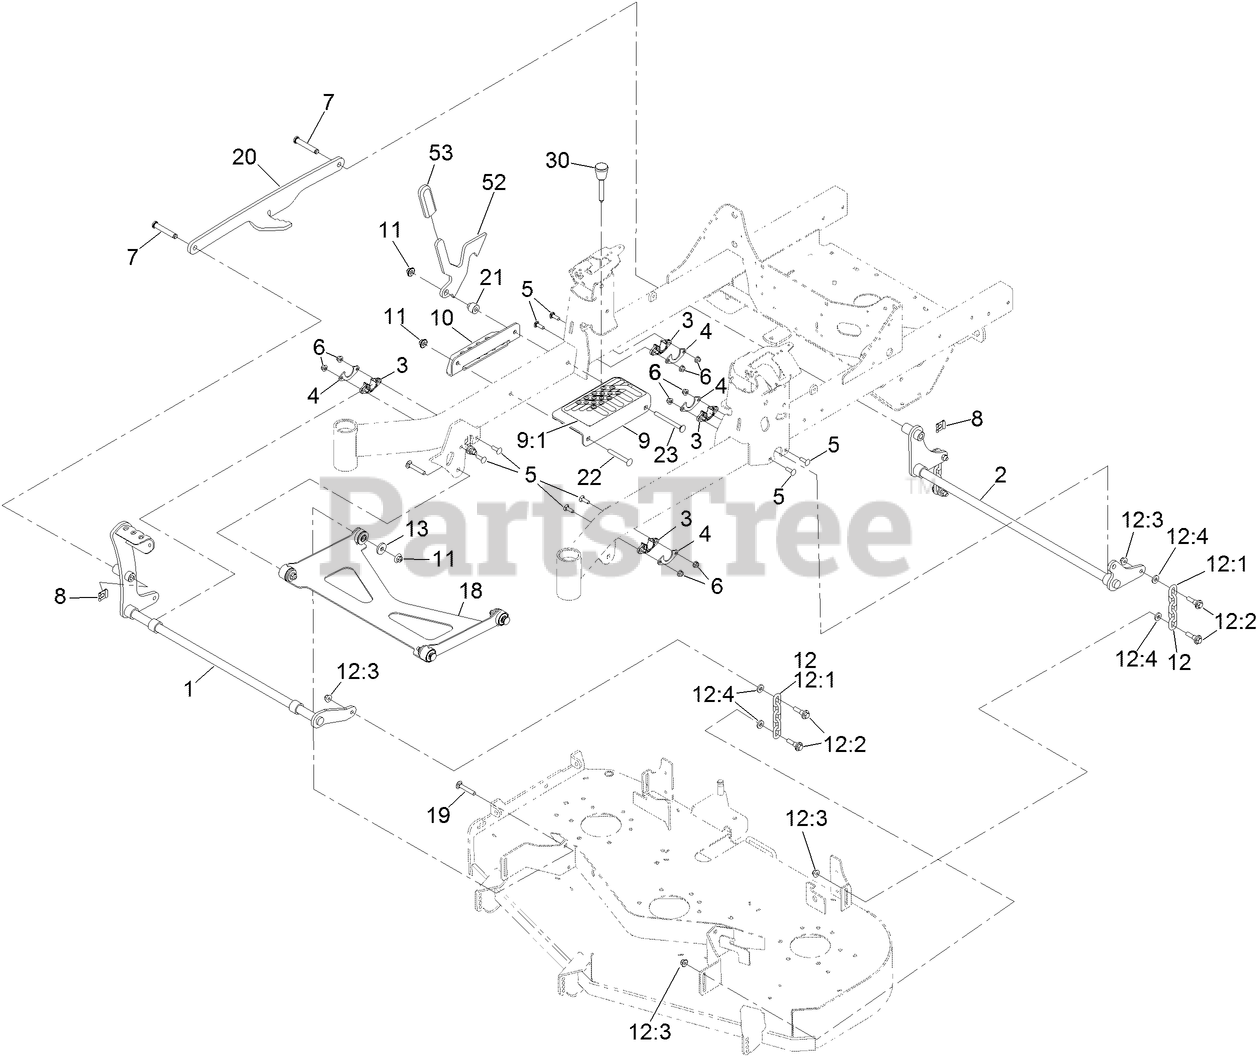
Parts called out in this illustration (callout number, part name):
1	SHAFT-LIFT, DECK
2	SHAFT-LIFT, DECK (REAR)
3	BUSHING-FLANGE
4	GUSSET-LIFT, DECK
5	SCREW-CARR
6	NUT-HF, NI
7	PIN-CLEVIS
8	CLIP-PIN
9	BRACKET ASM
9:1	DECAL-HOC
10	ANGLE-HOC, LOWER
11	NUT-FLANGE, NI
12	DECK CHAIN ASM
12:1	CHAIN-LIFT, DECK
12:2	BOLT-SHOULDER
12:3	NUT-HF, NI
12:4	SPACER
13	WASHER
18	DECK STRUT ASM
19	SCREW-CARR
20	LINK-LIFT
21	SPACER-STEPPED
22	SCREW-CARR
23	SCREW-CARR
30	PIN-HOC
52	PLATE-TRANSPORT LOCK
53	GRIP-LEVER
